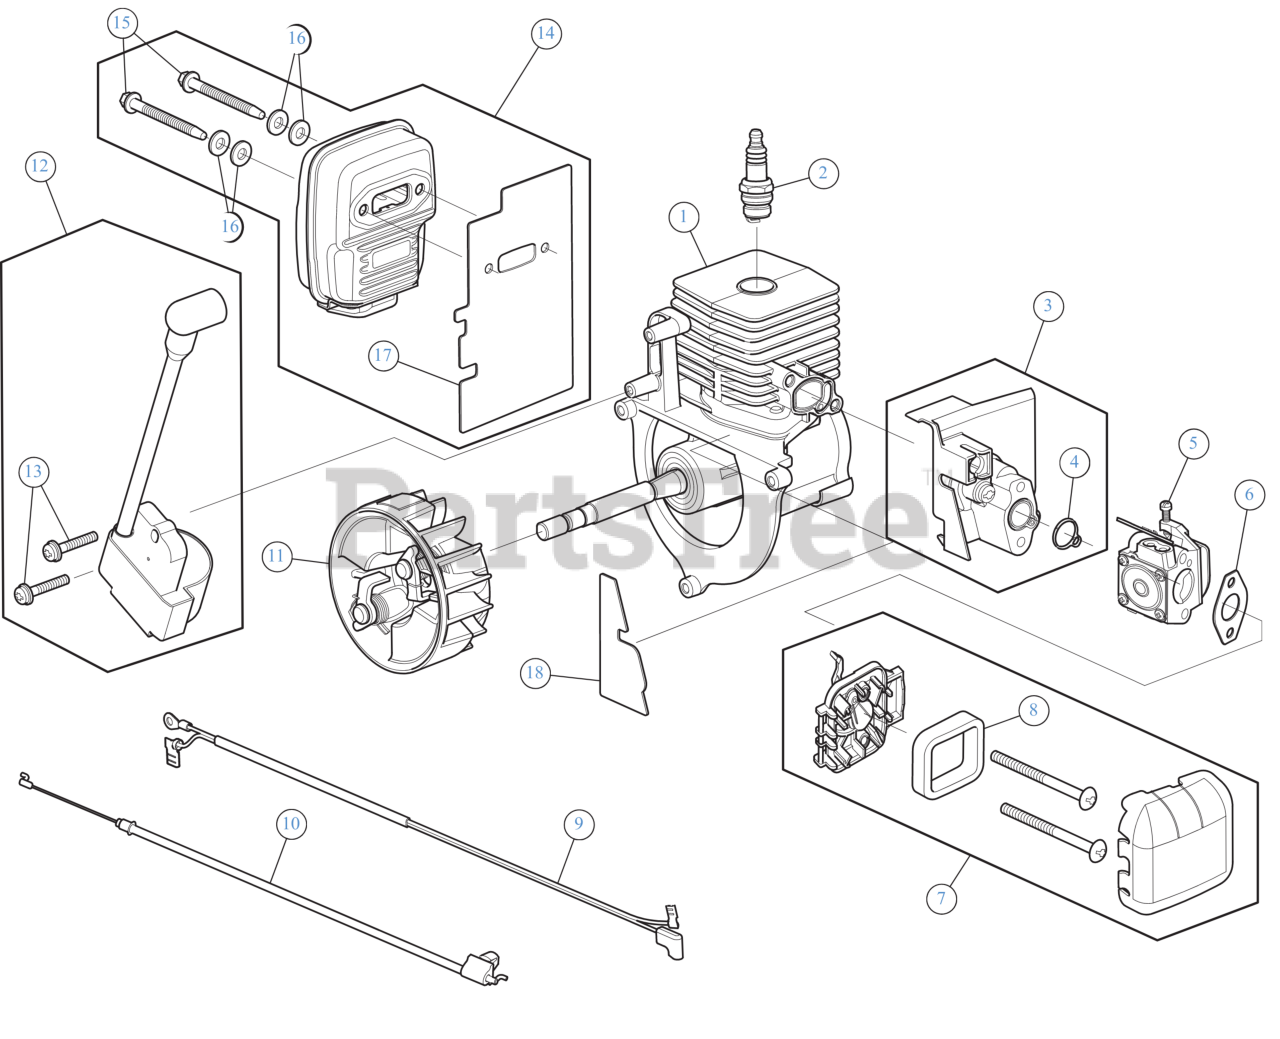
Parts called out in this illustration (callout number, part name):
1	SHORT BLOCK
2	SPARK PLUG
3	INTAKE ASSEMBLY
5	CARBURETOR
6	GASKET CARB
7	AIR CLEANER ASSEMBLY
10	THROTTLE CABLE
11	FLYWHEEL ASSEMBLY
12	MODULE
13	SCREW 8-32X.750
14	MUFFLER ASSEMBLY
15	MUFFLER SCREW
16	WASH, FLAT .480X.1
18	SHORTBLOCK GASKET
